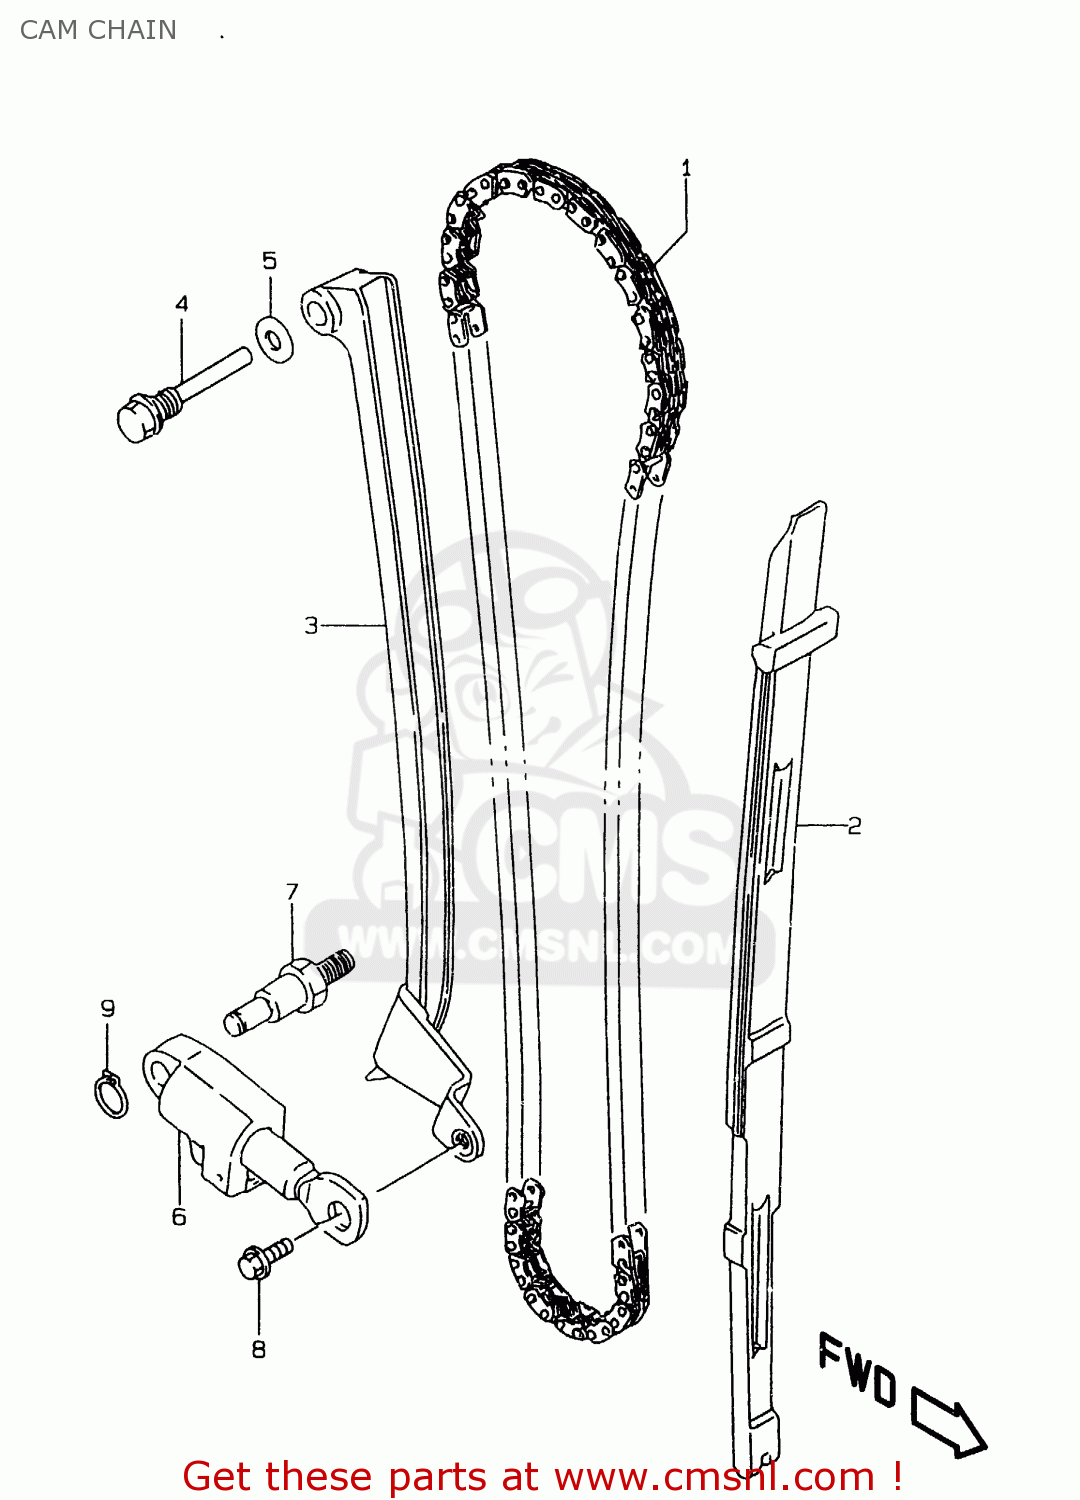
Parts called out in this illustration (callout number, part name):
1	CHAIN,CAMSHAFT DRIVE
2	GUIDE,CAM CHAIN
3	TENSIONER,CAM CHAIN
4	BOLT,CAM CHAIN TENSIONER
5	GASKET 8.2X14X1 (NAS)
6	ADJUSTER ASSY,TENSIONER
7	BOLT,STUD
8	BOLT
9	CIRCLIP
